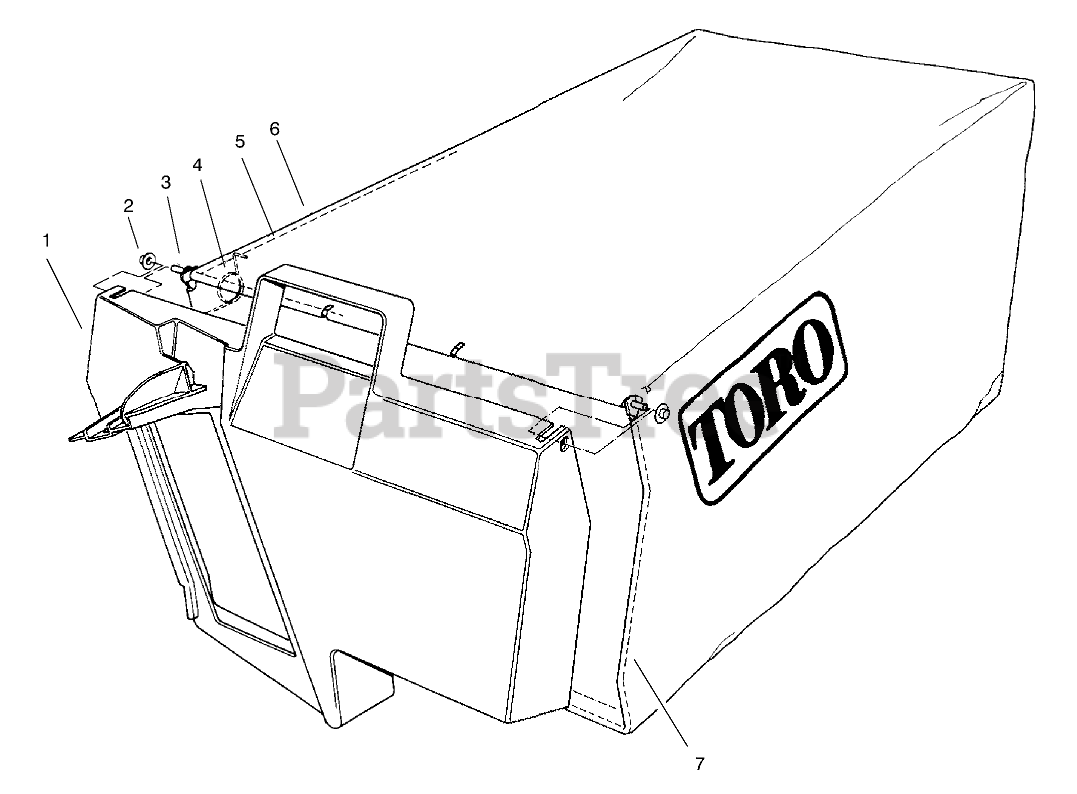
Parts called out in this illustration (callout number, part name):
1	DOOR-BAG, GRASS
2	NUT-PUSH
3	HINGE-DOOR, BAG
4	SPRING
5	FRAME-BAG, UPPER
6	Bag-Grass
7	FRAME-BAG
